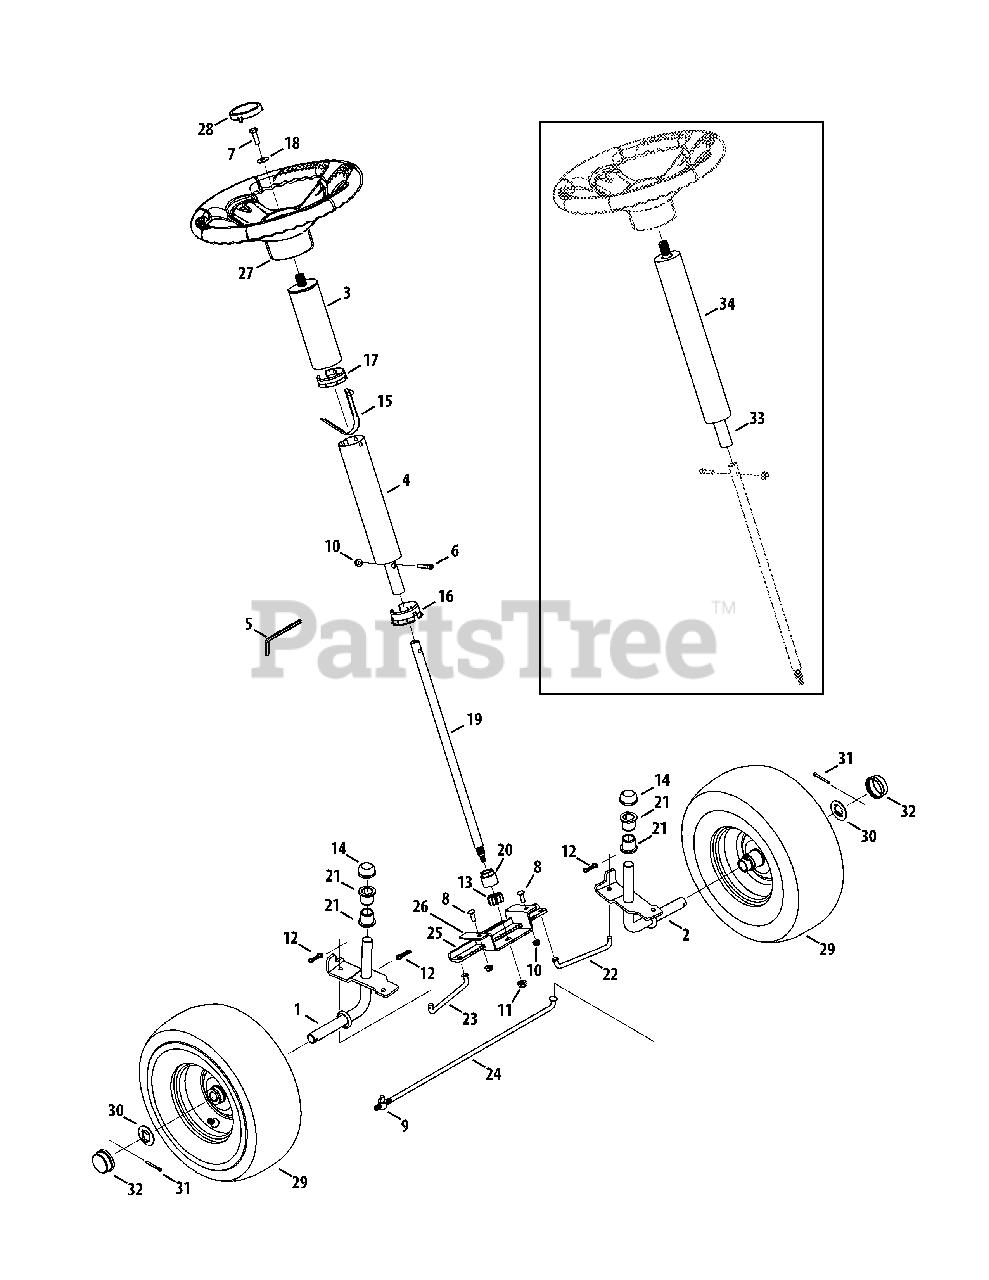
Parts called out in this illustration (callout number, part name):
1	Front Axle Assembly, RH
2	Front Axle Assembly, LH
3	Upper Tube Assembly
4	Lower Tube Assembly
5	Allen Wrench, 3/16
6	Screw, 1/4-20 X 1.25
7	Hex Head Screw, 5/16-18:1.00
8	Carriage Screw, 1/4-20, .75
9	Ferrule, 5/16-24 X .312 Dia.
10	Flange Lock Nut, 1/4-20
11	Flange Lock Nut, 3/8-16
12	Bow-Tie Cotter Pin, 72
13	Steering Pinion Gear
14	Push Cap, 3/4
16	Lower Steering Collar
17	Upper Steering Collar
18	Bevel Washer, .340X.872X.060
19	Steering Shaft, .625 OD X 18.03
20	Hex Flange Bearing, 5/8
21	Flange Bearing, .760 X .941 X 1.0
22	Steering Rod, LH
23	Steering Rod, RH
24	Front Tie Rod
25	Steering Rack Plate
26	Lower Steering Bearing
27	Steering Wheel, Standard Grip
27	Steering Wheel, Soft Grip
28	Cap, Troy-Bilt
30	Washer, .781 x 1.59
31	Cotter Pin, 5/32 x 1.25
33	Tube Assembly, Non-Telescoping
34	Steering Sleeve
